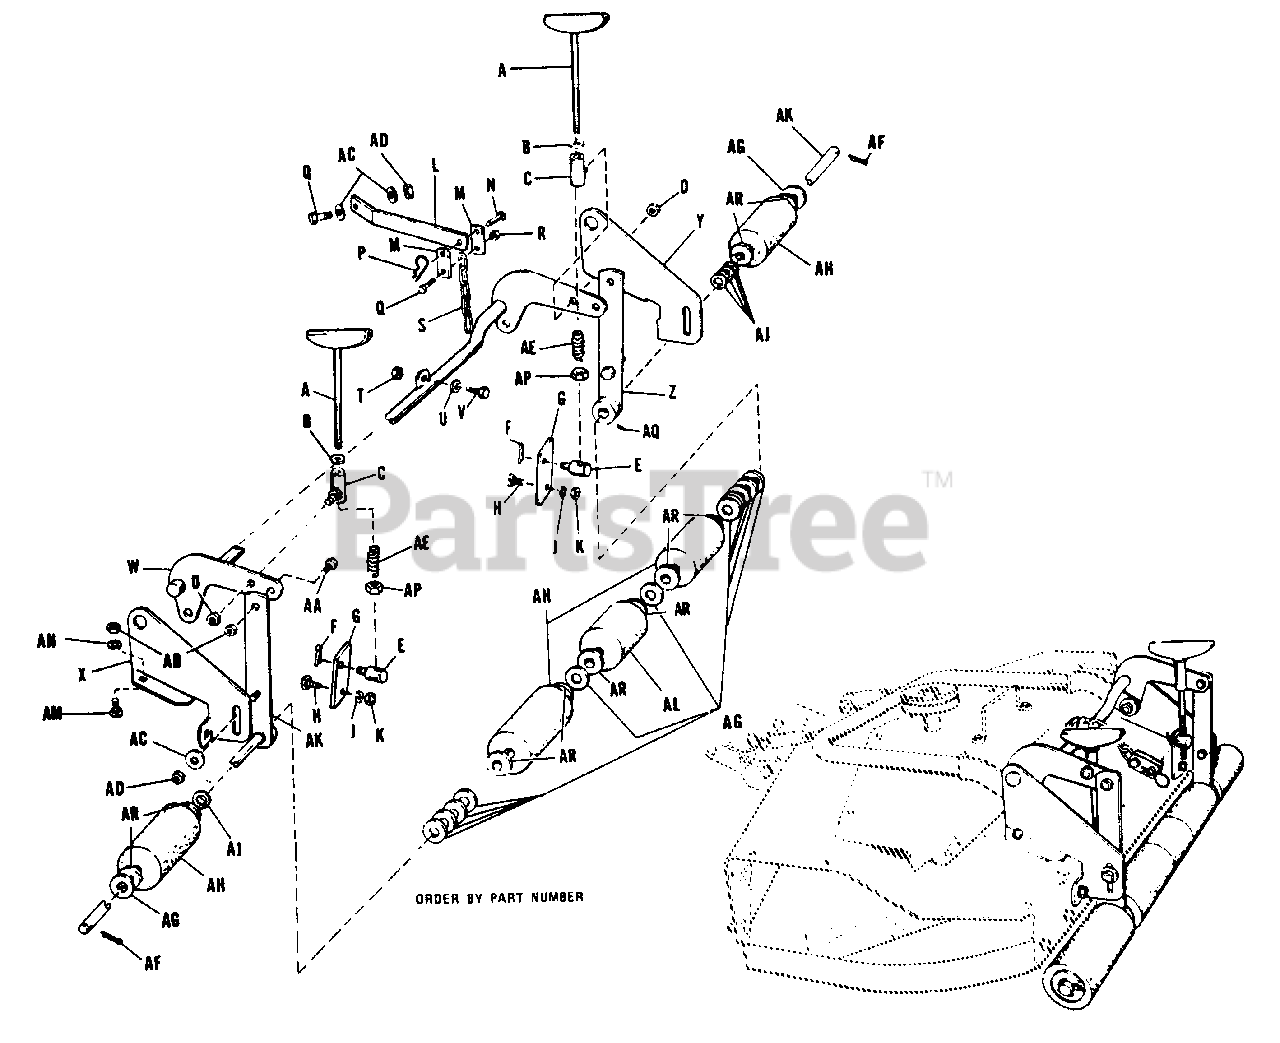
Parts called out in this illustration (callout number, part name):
A	Screw Assembly, Adjusting
B	Washer, Plain, 3/8"
C	Socket Assembly, Crank
D	Nut, Hex, Full, Lock, 3/8"-16 NC
F	Cotter Pin, 3/32" x 3/4" lg.
G	Link, Lift
H	Bolt, Carriage, 3/8"-16 NC x 3/4" lg.
J	Washer, Lock, 3/8"
K	Nut, Hex, Full, 3/8"-16 NC
L	Lever, Mower Lift
M	Link, Mower Lift
P	Clip, Spring
Q	Capscrew, Hex Hd., 3/8"-16 NC x 1" lg.
R	Nut, Hex, Full, Lock, 3/8"-16 NC
T	Nut, Hex, Full, Lock, 3/8"-16 NC
U	3/8" Washer
V	Capscrew, Hex Hd., 3/8-16 x 1" lg.
W	Arm Assembly, Rocker
X	Bracket, Roller, R.H.
Y	Bracket, Roller, L.H.
Z	Bar Assembly, Roller
AA	Capscrew, Hex Hd., 3/8"-16 NC x 1" lg.
AB	Nut, Hex, Full, 3/8"-16 NC
AC	Washer, Plain, 3/8"
AD	Nut, Hex, Full, Lock, 3/8"-16 NC
AE	Spring, Adj. Screw
AF	Pin, Cotter, 3/16" x 1" lg.
AH	Roller W/Bushing
AK	Shaft & Support Arm.
AL	Roller W/Bushing
AM	Bolt, Carriage, 3/8"-16 NC x 3/4" lg.
AN	Washer, Lock, 3/8"
AP	Nut, Hex, Full
AQ	Set Screw
